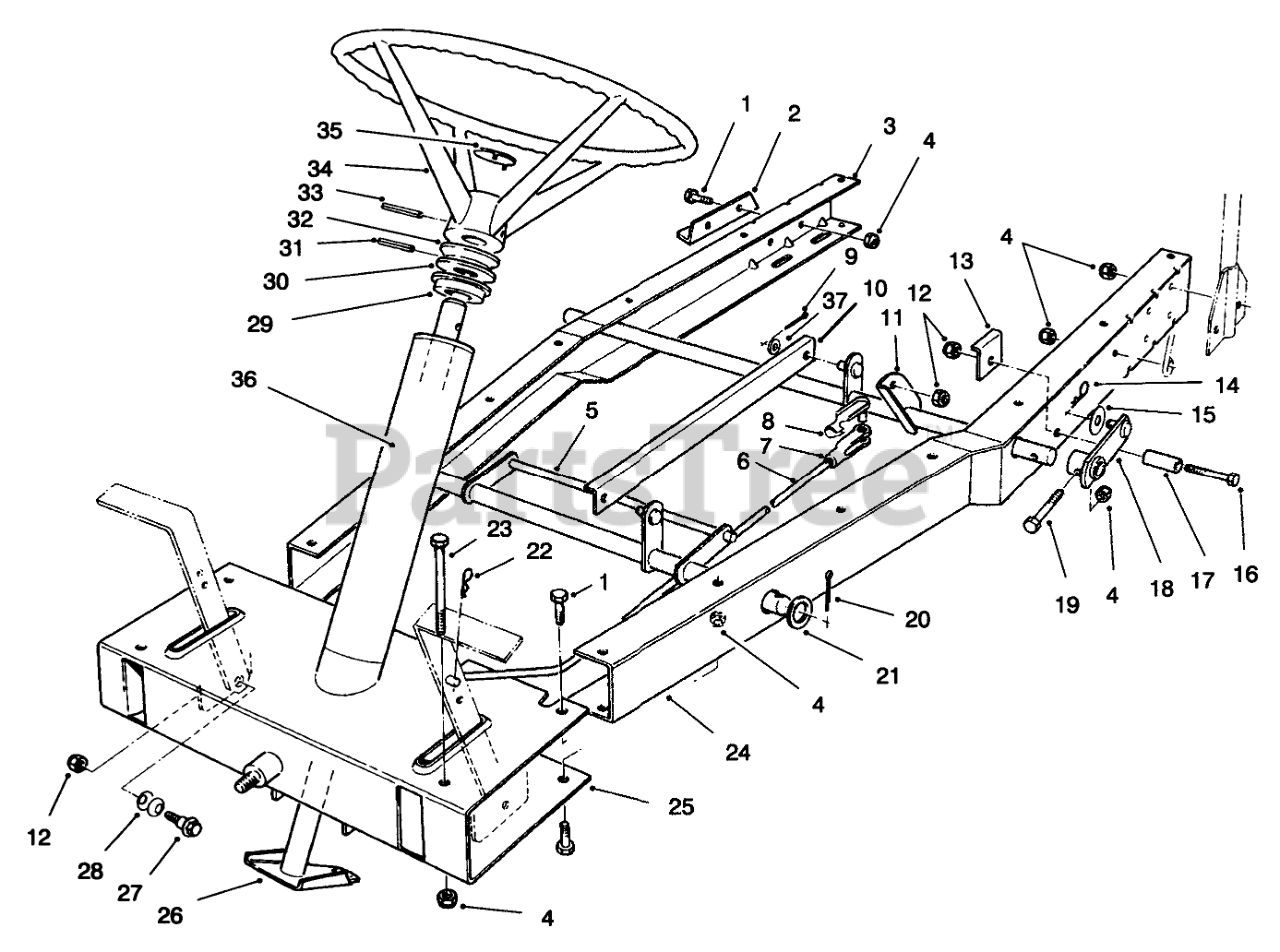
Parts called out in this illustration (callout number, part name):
1	SCREW-HH
2	MOUNT-AXLE BRG
3	FRAME-CHANNEL RH RED
4	NUT-LOCK, NI
5	Lift W.A.-Front, Deck
6	ROD-CLUTCH
7	CLEVIS-ADJ
8	CLEVIS PIN ASM
9	PIN-COTTER
10	LINK-HOC BRACKET
11	REAR SUP TUBE WA RED
12	NUT-LOCK, NI
13	DECK STOP BRACE (BLACK)
14	PIN-HAIR
15	WASHER
16	SCREW-HH
17	SPACER-STOP,DECK
18	HOC LEVER WA
19	AXLE MTG BOLT
20	PIN-COTTER
21	WASHER-FLAT
22	PIN-COTTER
23	SCREW-HH
24	FRAME-CHANNEL LH
25	FRONT FRAME WA RED
26	STEERING SHAFT WA BLK
27	BOLT-SHOULDER
28	WASHER-BELLEVILLE
29	BUSHING-STEERING
30	WASHER-STEERING
31	PIN-ROLL
32	SPACER-STEERING
33	PIN-ROLL
34	STEERING WHEEL ASM
35	INSERT - STRG WHL F/W
36	DECAL - STEERING COLUMN
37	WASHER-FLAT
